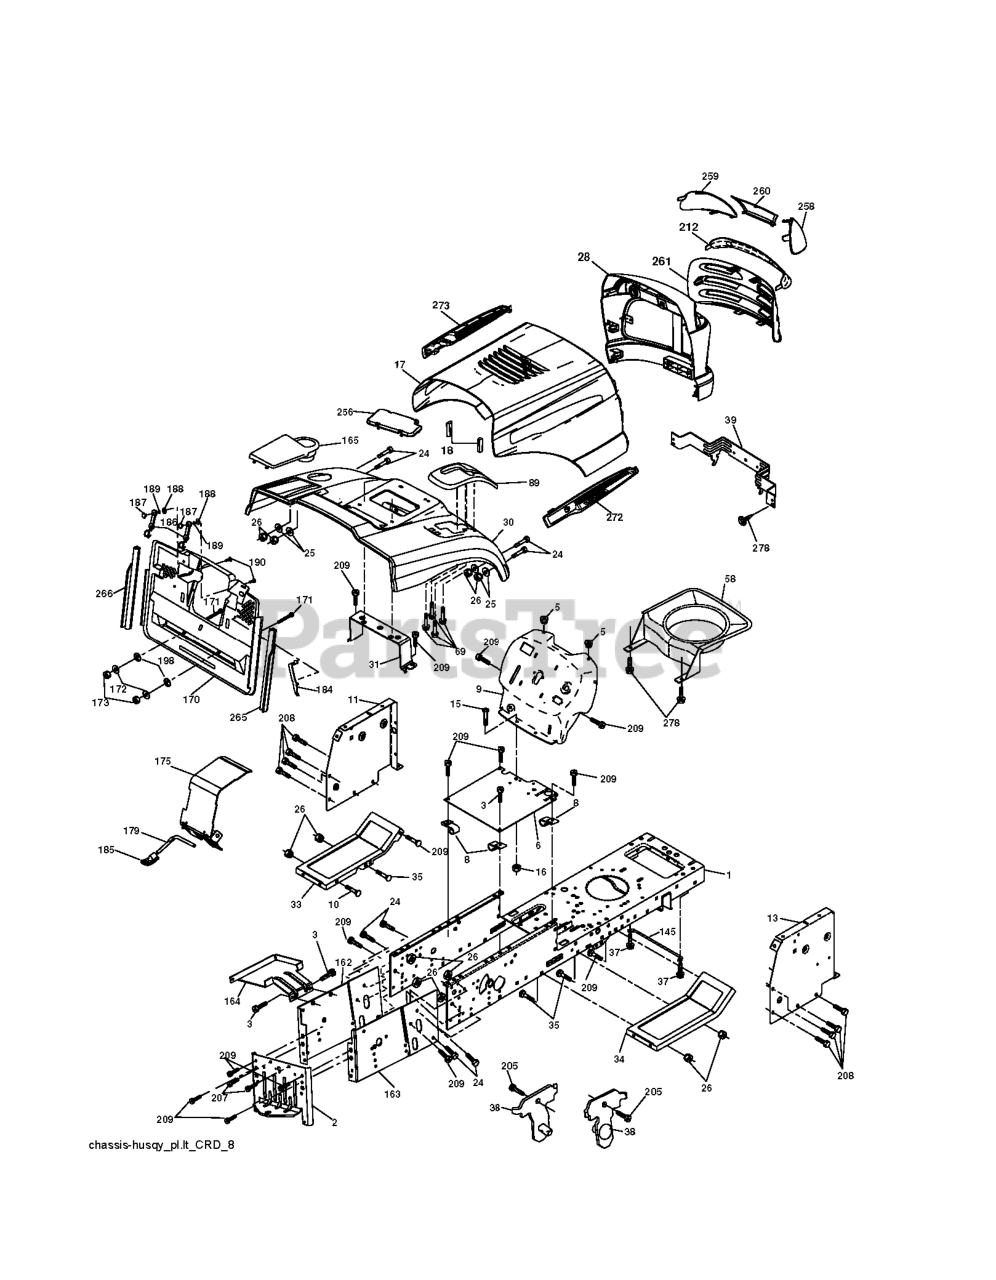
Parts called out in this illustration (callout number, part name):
2	DRAWBAR
3	SCREW 3/8-16X3/4
5	BUMPER.RUBBER.HOOD
6	PLATE
8	CLIP,INSULATOR
10	BOLT D
11	PANEL.DASH.LH.LTX
13	PANEL ASM, DASH RH
15	Screw, Machine, Truss Head 5/16-18 UNC x 3/4
16	NUT
17	VENT.HOOD.LASER.III
18	BUMPER.HOOD.LARGE.1.75"
25	WASHER
26	NUT
30	CONSOLE.CRD.AUTO.GRY
31	BRACKET SUPPORT FENDER
33	FOOTREST PNT LH
34	FOOTREST PNT RH
37	Screw 5/16-18 x 1/2 Hex, Self Tapping 5/16-18 x 1/2
38	BRACKET ASM PIVOT MOWER REAR
39	BRACKET PIVOT LASER
69	SCREW.HI-LO.CONSOLE
89	CONSOLE.CRD.AUTO.GREY.2005
145	ROD PIVOT CHASSIS/HOOD
162	BRACKET
163	BRACKET EXTEN CHASSIS RH CRD
165	RP.COVER.BATTERY.CRD.GREY
172	WASHER
175	DOOR TRAP
179	ROD PIVOT FBI
184	BRACKET.ACTUATOR.BAGGER.SRD
186	LATCH ASSY
187	WELDNUT
189	LOCKWASHER #10
190	SCREW
207	SCREW, 5/16-18 X 1/2
208	SCREW 3/8-16X1/2
209	SCREW, 3/8-16X3/4
212	INSERT.LENS.REFLECTIVE
256	COVER FENDER CRD
258	LENS LH
259	LENS LH
260	COVER.LENS.HUSQ.LASER
265	SEALING
266	SEALING
272	VENT.HOOD.LASER.
273	VENT.HOOD.LASER.
278	SCREW
